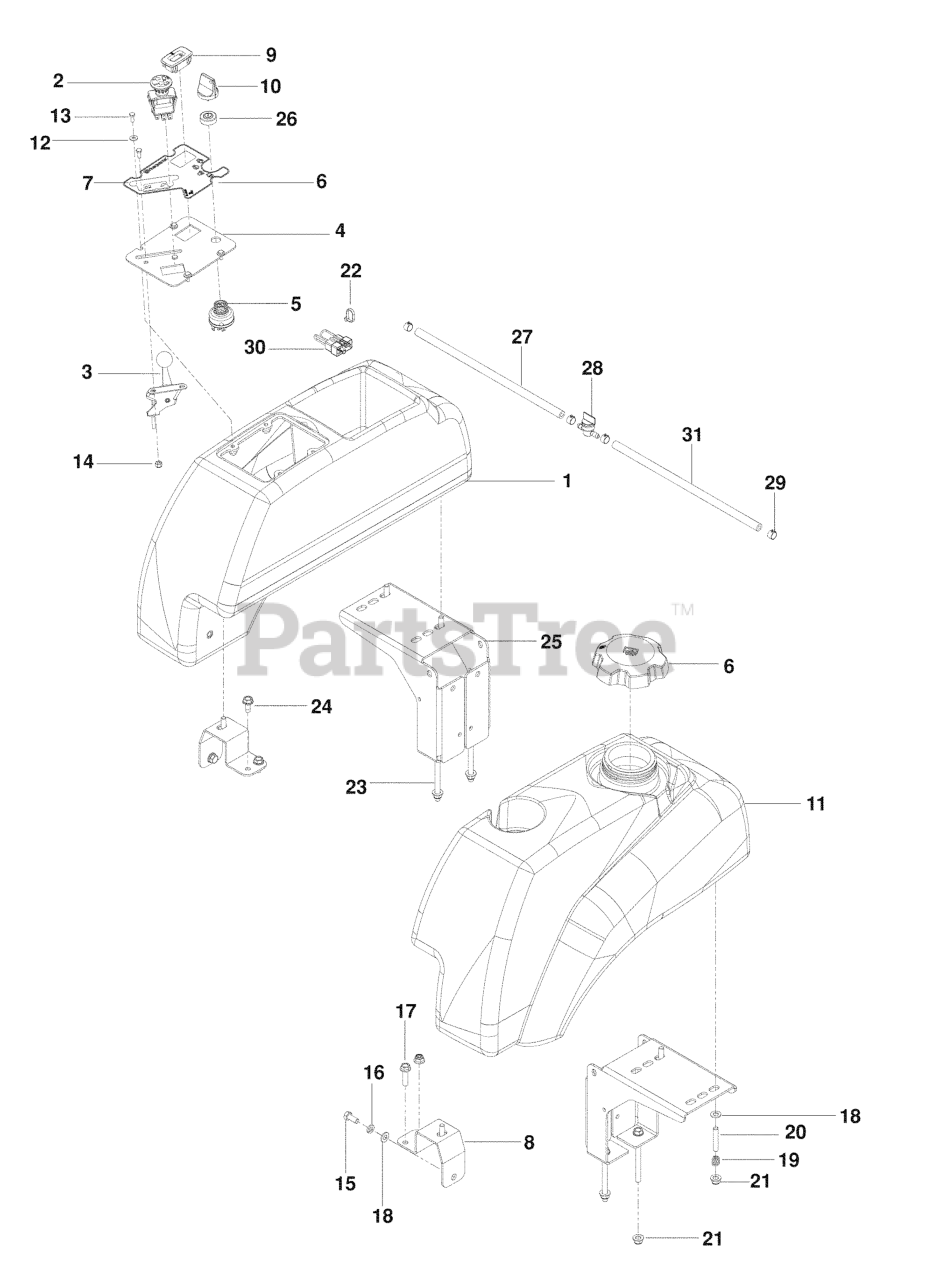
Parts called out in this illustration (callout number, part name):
1	FENDER CONSOLE
2	SWITCH, PTO 10 AMP
3	THROTTLE CABLE
4	RP.PLATE, CONSOLE, BLK
5	SWITCH, IGNITION, INDAK
6	FUEL CAP, HTC
7	DECAL, CONSOLE
8	SUPPORT, TANK, BLK
9	HOUR METER
10	KEY, IGNITION
11	LEFT TANK W/CUP HOLDER
12	WASHER #10
13	HCS #10-24 X 1/2
14	NUT 10-24 NYLOC
15	HCS 5/16C X 3/4
16	WASHER.LOCK.HVY.HLCL.SPR.5/16
17	HHFS 5/16-18 X 1.25 TPBLT GD 5
18	FLAT WASHER 5/16 SAE
20	STUD, 5/16C
21	5/16-18 NYLOC FLANGE NUT
22	TIE, PLASTIC
23	HHFS 5/16-18 X 3 3/4
24	BOLT 5/16-18 X 3/4
25	MOUNT, TANK, ZT BLK
26	CAP IGNITION NUT
27	FUEL LINE 13"
28	FUEL VALVE
29	HOSE CLAMP
30	PLUG, TIMER
31	FUEL LINE 18"
